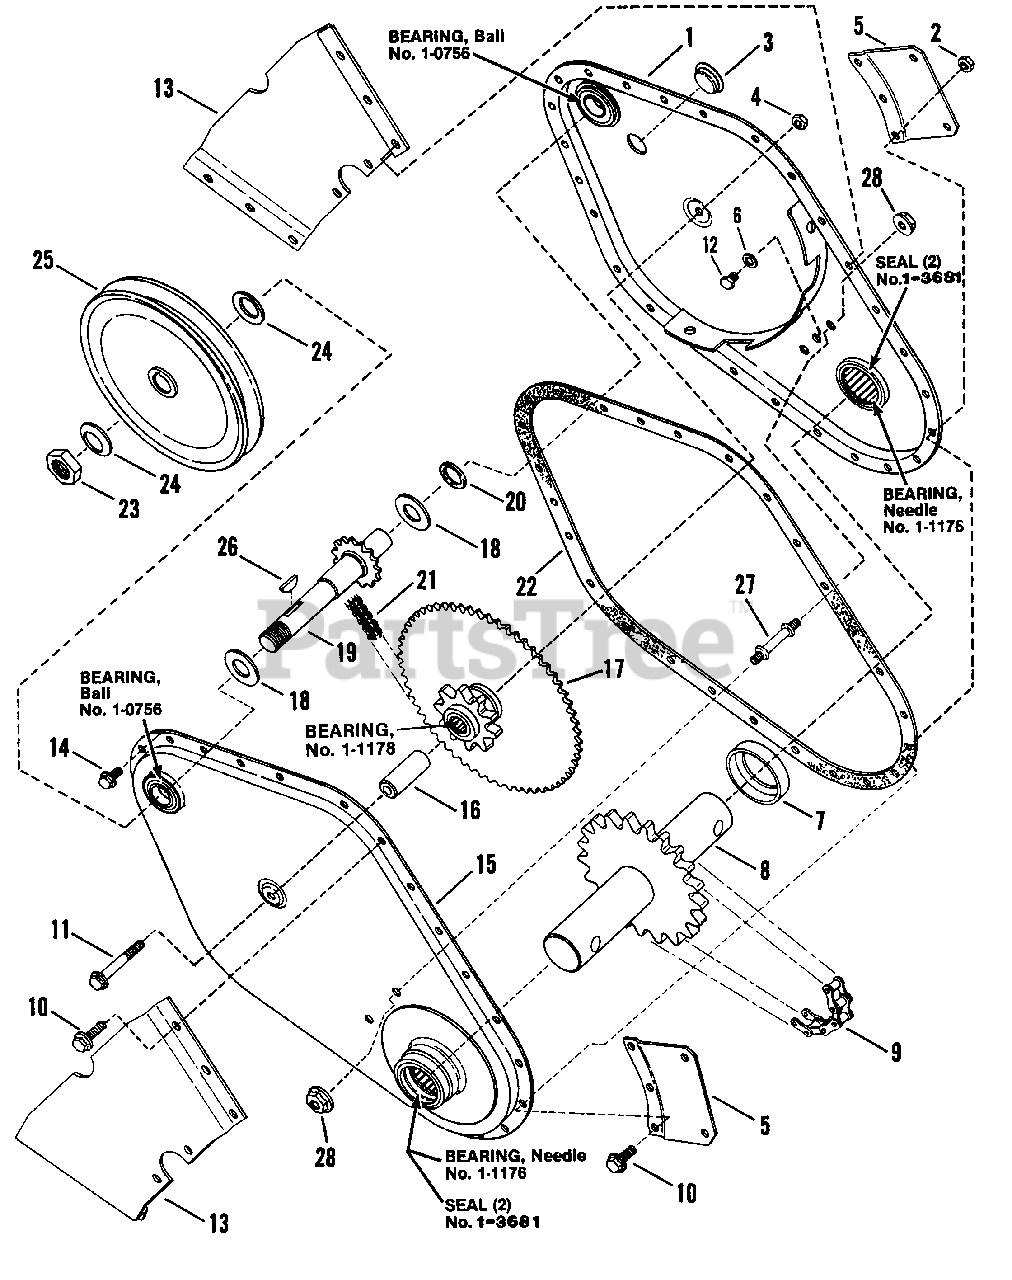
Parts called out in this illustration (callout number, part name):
1	ASSEMBLY, Case R.H.
2	NUT, 5/16-18 Hex Center Lock
3	PLUG, 3/4"
4	NUT, 5/16-24 Hex Lock
5	RETAINER, Depth Bar
6	WASHER, Seal
8	SHAFT, Tine Rotor
9	CHAIN, Drive- #50
10	SCREW, 5/16-18 x 3/4" Hex Head Cap, Grade 2
11	SCREW, 5/16-24 x 2-1/4" Hex Head Cap, Grade 5
12	SCREW, 5/16-18 x 3/8" Hex Washer Self-Tap
13	PLATE, Wear Guard
14	SCREW, 5/16-18 x 1/2" Hex Washer Self-Tap
15	(NLA) ASSEMBLY, Case L.H.
16	RACE, Sprocket Bearing
17	SPROCKET, Intermediate
18	WASHER, Shim
19	SHAFT, Drive
20	O-RING, 5/8" I.D. x 1/16"
21	CHAIN, Drive- #35
22	GASKET, Case Housing
23	NUT, 5/8-18 Hex Jam Center Lock
24	WASHER, Cone
25	PULLEY, 6" O.D.
26	KEY, 3/16" x 3/4" Woodruff (#9)
27	STUD, Spacer
28	NUT, 5/16-18 Hex Flange Lock
